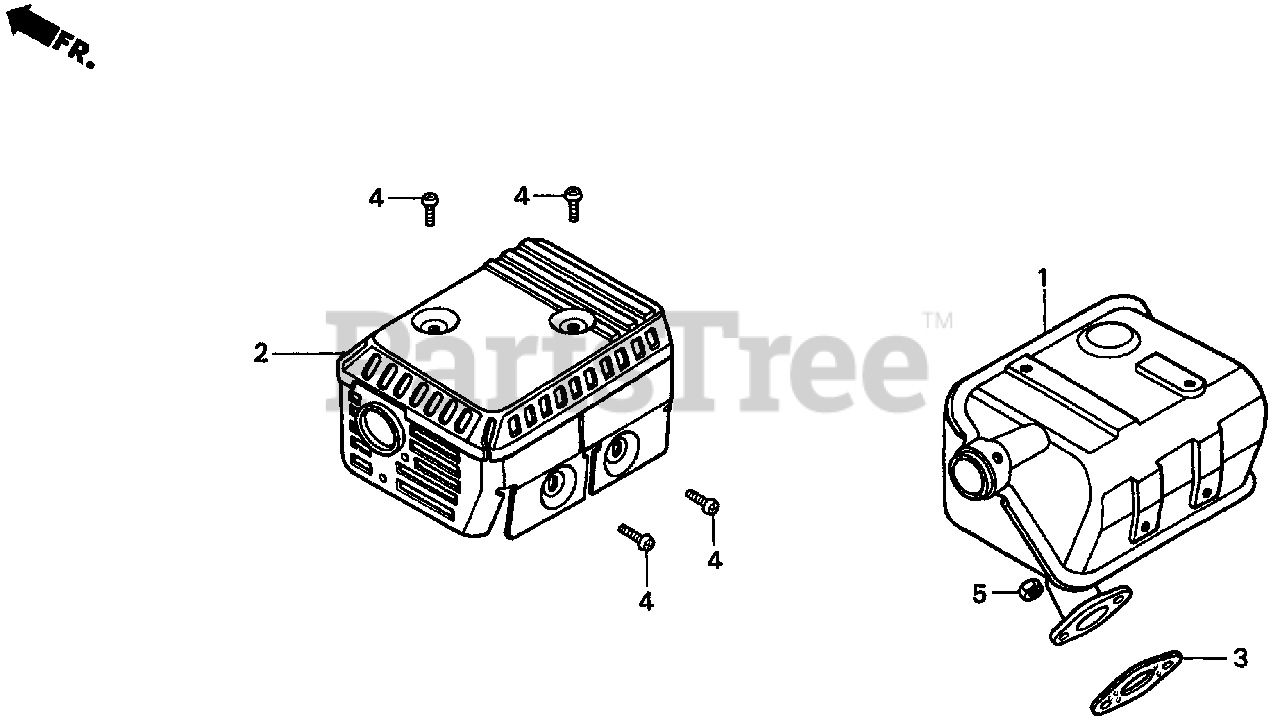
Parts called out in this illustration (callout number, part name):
1	MUFFLER
2	PROTECTOR, MUFFLER
3	GASKET, MUFFLER
4	SCREW, TAPPING (5X8)
5	NUT, HEX. (8MM)
